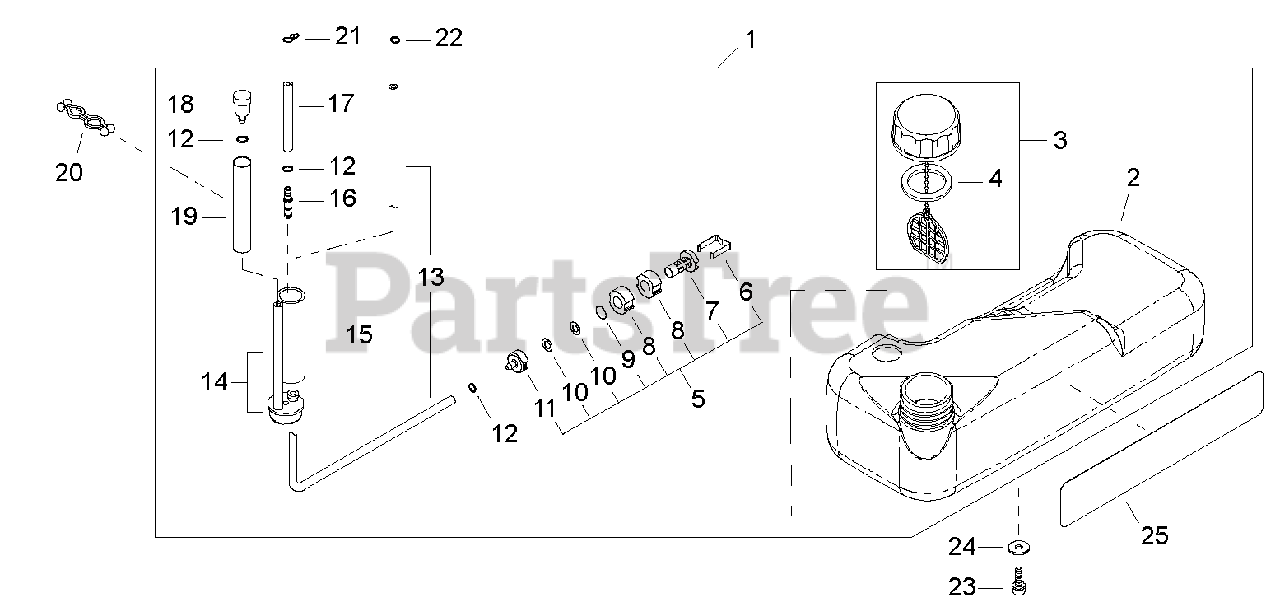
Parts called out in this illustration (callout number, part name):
1	TANK ASSY, FUEL
2	TANK, FUEL
3	CAP ASSY, FUEL
4	GASKET, FUEL CAP
5	FILTER, FUEL
6	CLIP, FILTER
7	BODY, FUEL FILTER
8	FILTER, FUEL
9	RING, RETAINING
10	SCREEN, FILTER
11	WEIGHT, FUEL LINE
12	CLIP Ø6
13	PIPE, FUEL
14	GROMMET, FUEL W/VENT PIPE
15	SLEEVE
16	CONNECTOR, PIPE
17	PIPE, FUEL RETURN
18	VENT ASSY
19	TUBE, INSULATOR
20	CLIP
21	CLIP, SPRING Ø5.2
22	CLIP Ø6
23	BOLT, ADHESIVE M5×14
24	WASHER Ø15ר5.2×1.6
25	LABEL, EB8520
